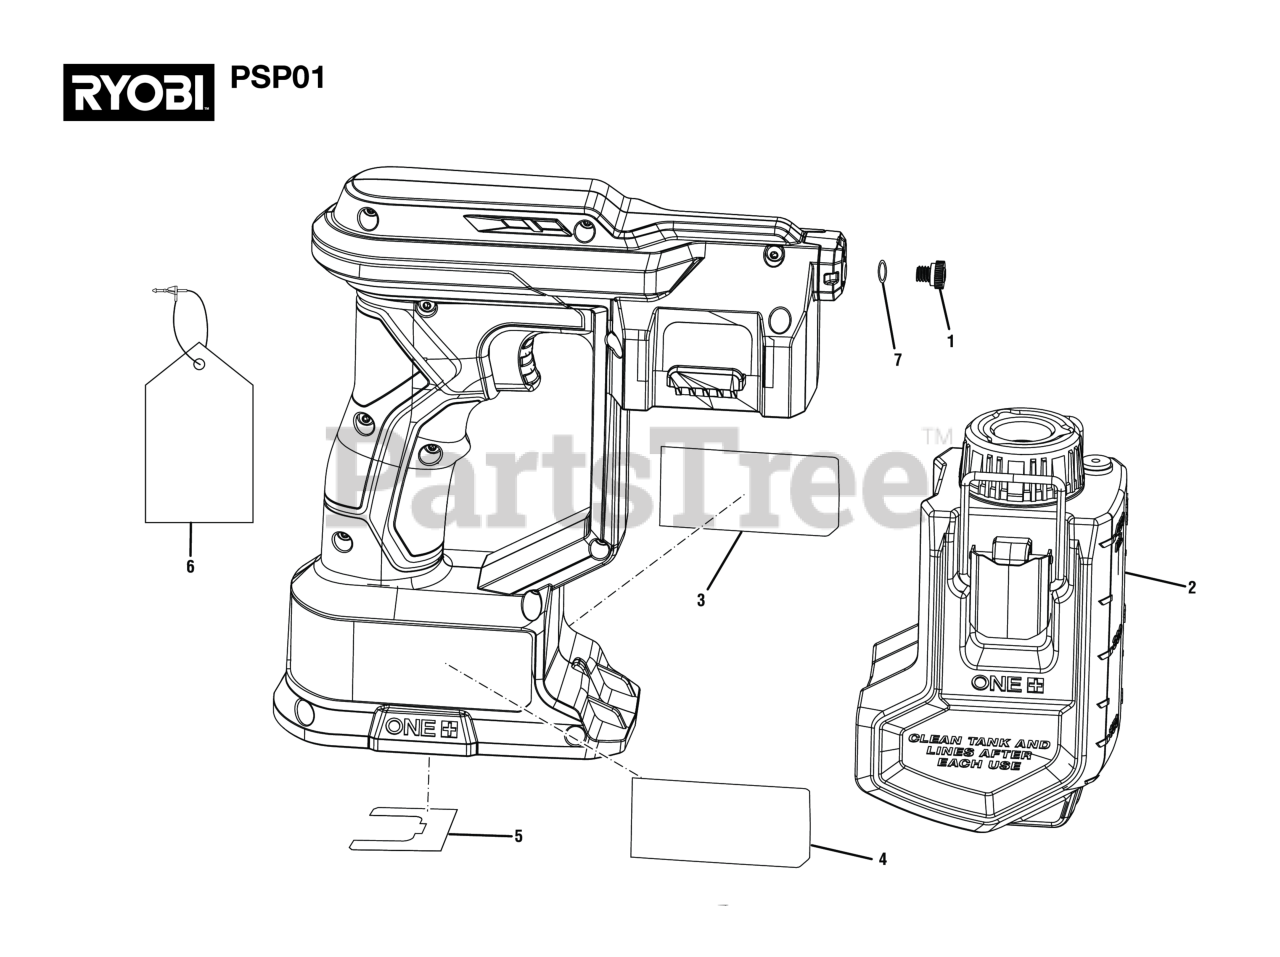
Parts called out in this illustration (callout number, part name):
2	Tank Assembly (Inc. Key Nos. 14 & 17-20)
3	Logo Label
4	Data Label
5	Warning Label
6	Hang Tag Assembly
